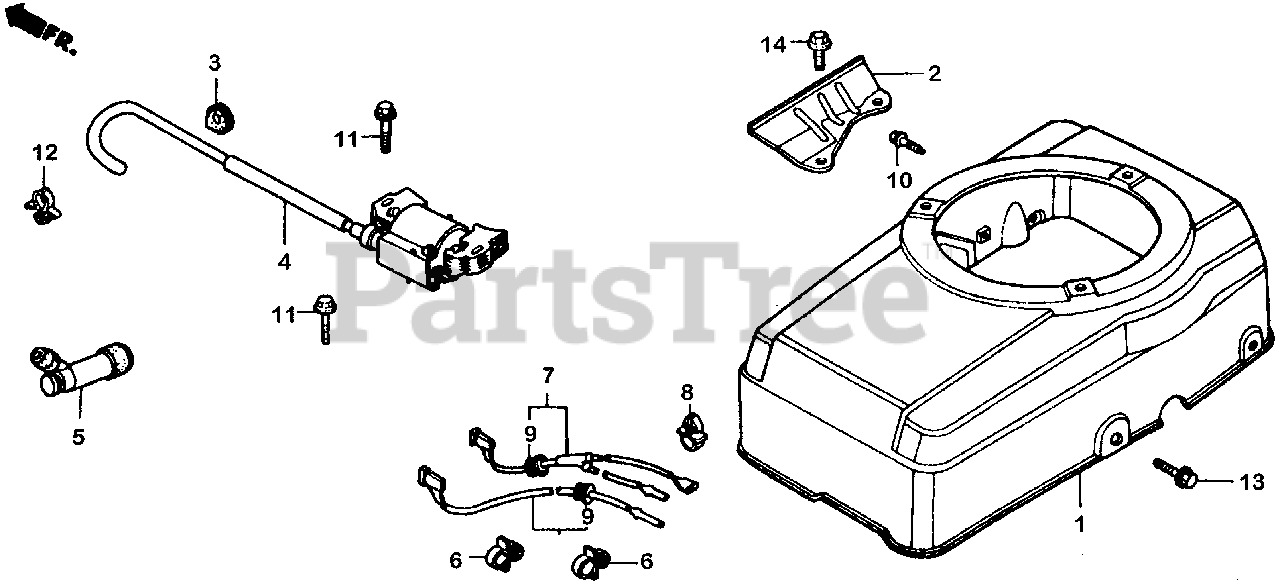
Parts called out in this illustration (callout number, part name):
1	COVER, FAN *R8* (BRIGHT RED)
2	PLATE, SIDE
3	GROMMET, CORD
4	COIL ASSY., IGNITION
5	CAP ASSY., NOISE SUPPRESSOR
6	CLIP, IGNITION WIRE (8MM)
7	WIRE, STOP SWITCH
8	HOLDER, STOP SWITCH WIRE
9	GROMMET, WIRE CORD
10	BOLT, FLANGE (6X12) (CT200)
11	BOLT, FLANGE (6X28) (CT200)
12	CLIP, HARNESS
13	BOLT, FLANGE (8X16)
14	BOLT, FLANGE (8X20)
